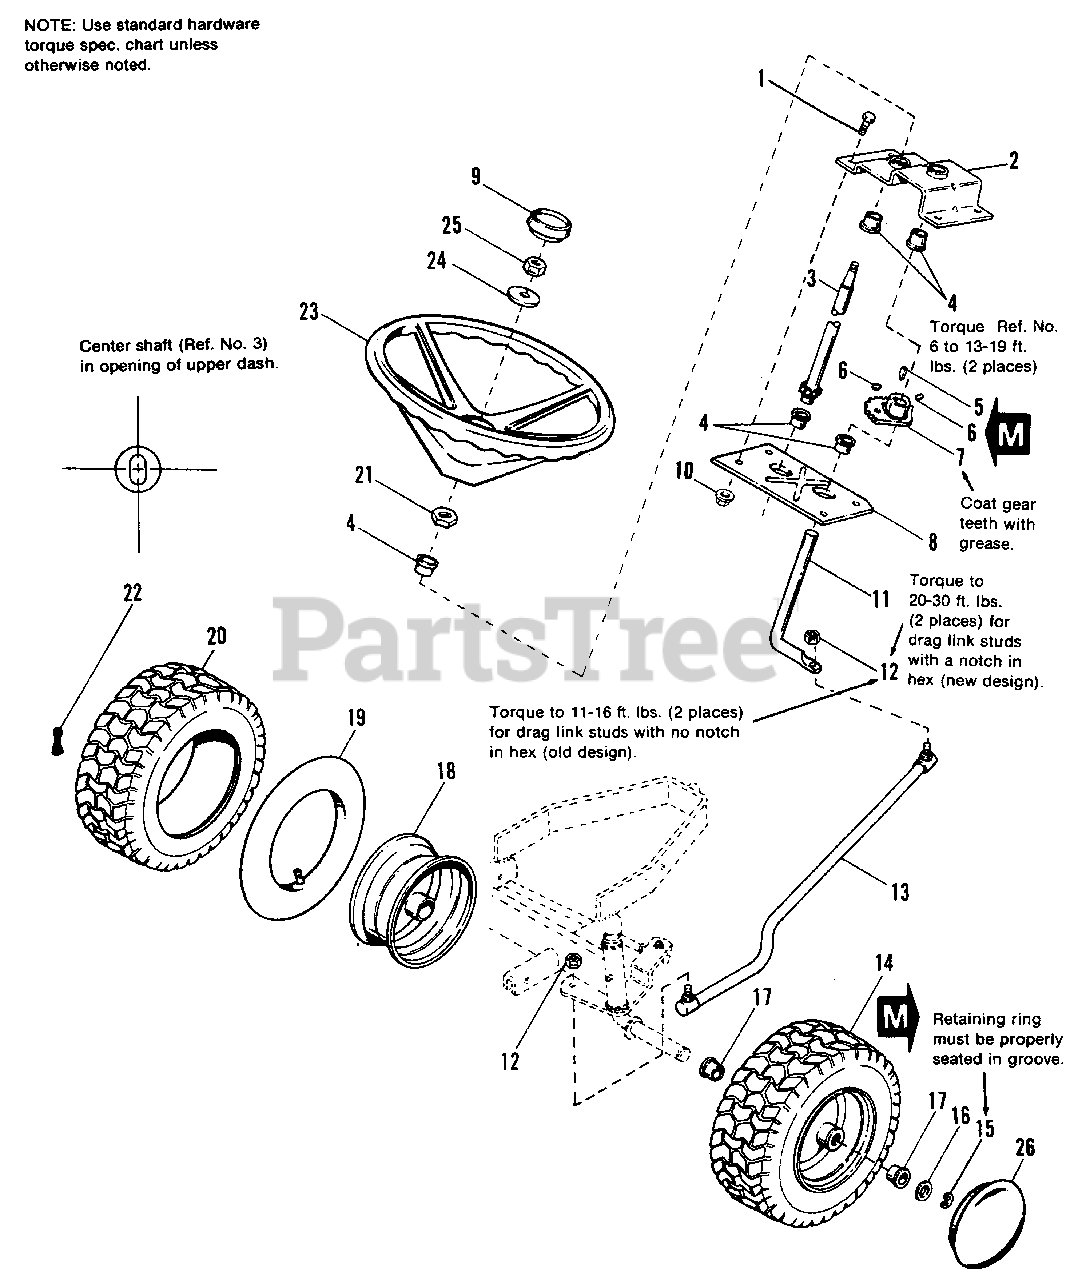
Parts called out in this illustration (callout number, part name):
1	CAPSCREW, Hex Hd., 5/16-18 x 3/4
2	PLATE, Steering
3	SHAFT ASSY., Steering
6	SETSCREW, 5/16-18 x 1/2
7	GEAR, Steering
8	PLATE, Base, Steering
9	CAP, Steering Wheel
10	LOCKNUT, Hex, Flange, 5/16-18
11	ROD, Steering
12	NUT, Special, 3/8-24
14	WHEEL & TIRE ASSY.
18	WHEEL ASSY.
19	TUBE, 4.10/3.50-6 (For Service Only)
20	TIRE, 13 x 6.50-6 (Carlisle)
21	WASHER, Hex
22	VALVE STEM & CAP
23	WHEEL, Steering (Incl. Ref. No. 21)
24	WASHER, Compression
25	LOCKNUT, Hex, 5/16-18
26	HUB CAP, Front
